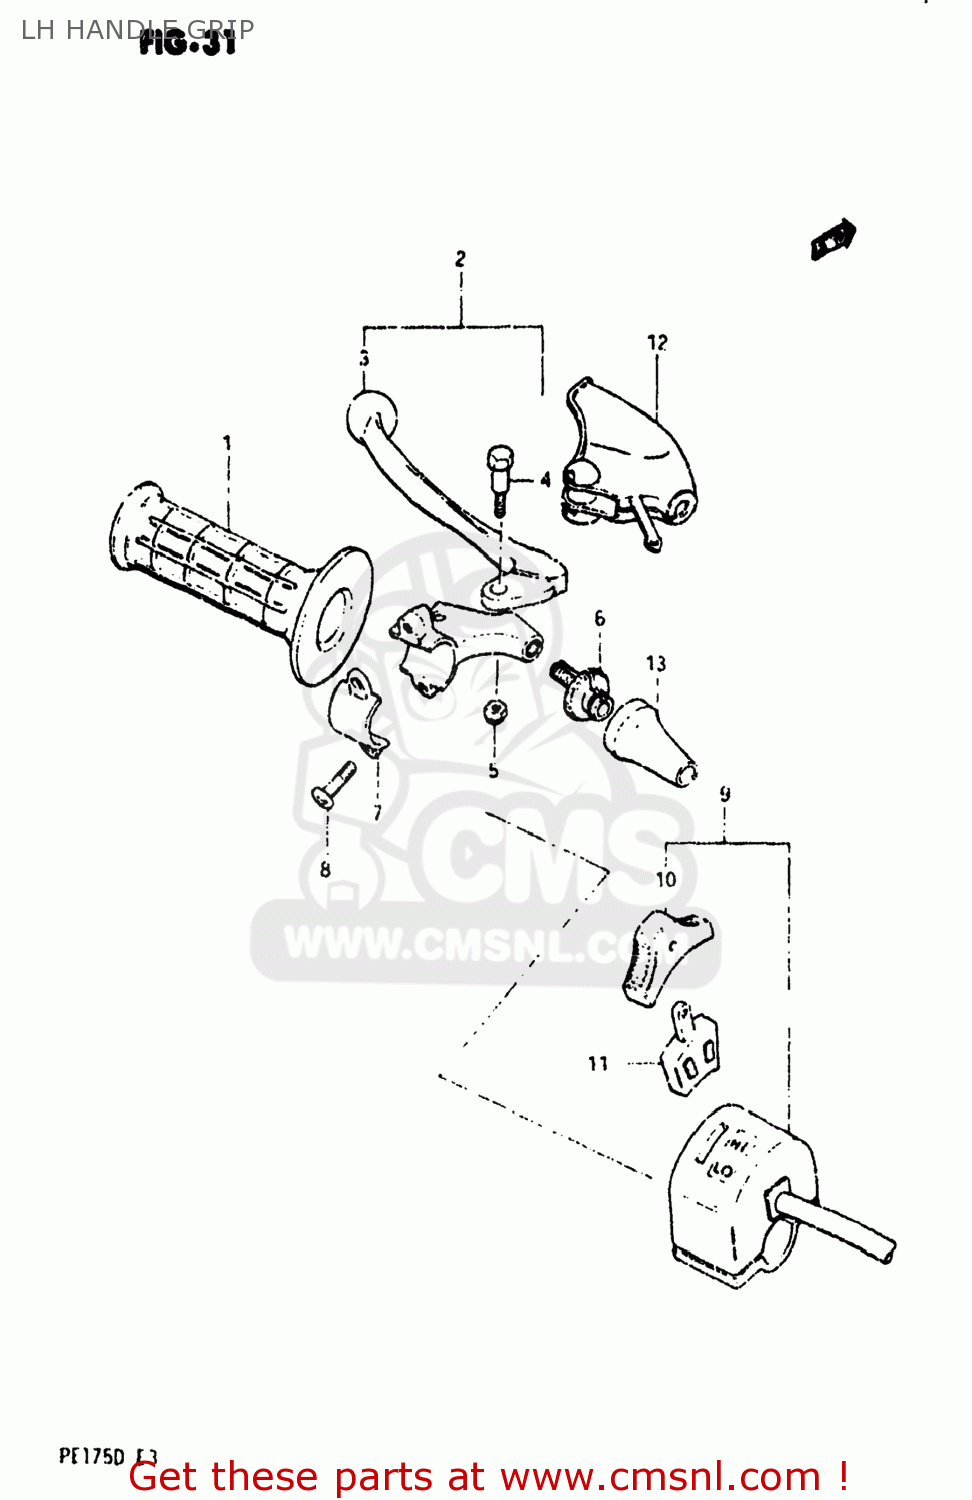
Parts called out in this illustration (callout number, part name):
1	GRIP,LEFT
2	LEVER ASSEMBLY,CLUTCH
3	LEVER,CLUTCH
4	BOLT,LEVER
5	NUT 6MM
6	ADJUSTER,CABLE
7	BRACKET,LEVER
8	SCREW
9	SWITCH,DIMMER
10	KNOB,LIGHTING & DIMMER
11	BLOCK,LIGHTING/DIMMER
12	COVER,BRAKE LEVER
13	BOOT,CLUTCH CABLE
